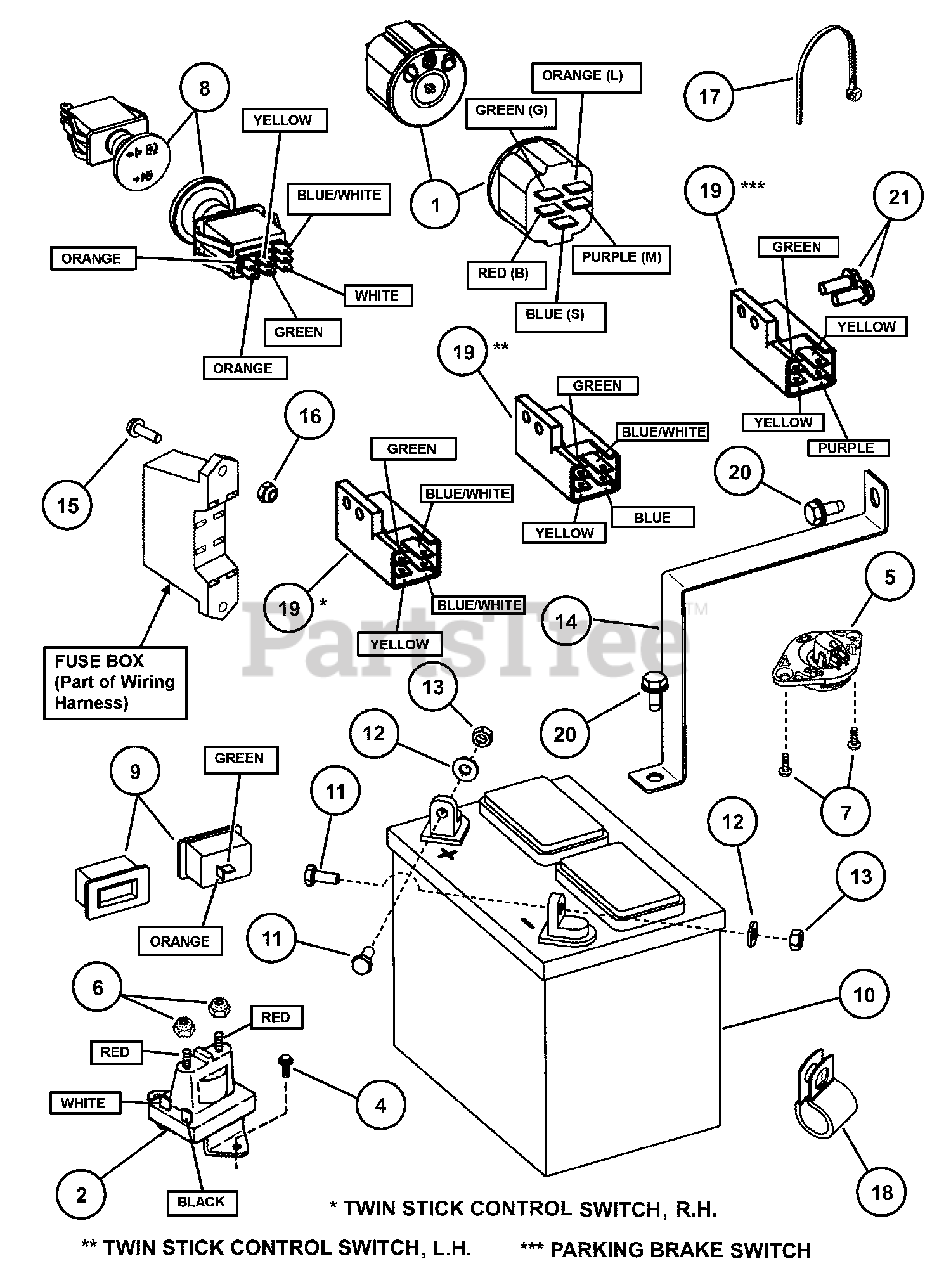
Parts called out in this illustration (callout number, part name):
1	SWITCH, Ignition
2	SOLENOID, Super Trombetta (2 Terminal)
4	SCREW, 1/4-20 x 1/2" Hex Washer Self-Tap
5	ASSEMBLY, Seat Switch (NC)
6	NUT, 1/4-20 HEX NYLON LOCK
7	SCREW, HEX WSHR HD PLAST .250 X .500 BLK
8	SWITCH, PTO, Yellow
9	HOUR METER w/Flash Alerts
10	BATTERY, 11 Plate 375CCA- Wet
11	SCREW, 1/4-20 x 5/8" Hex Head Cap, GR 5
12	WASHER, 1/4" Flat
13	NUT, 1/4-20 Hex Center Lock
14	BRACKET, Battery
15	SCREW, #10-32 x 5/8" Hex Washer Self-Tap
16	NUT, #10-32 Hex Nyloc
18	CLIP, Harness
19	SWITCH- DPDT (NC/NO)
20	SCREW, 5/16-18 x 5/8" Hex Washer Self-Tap
21	SCREW, #10-24 x 1/2" Hex Washer Self-Tap (Torx)
